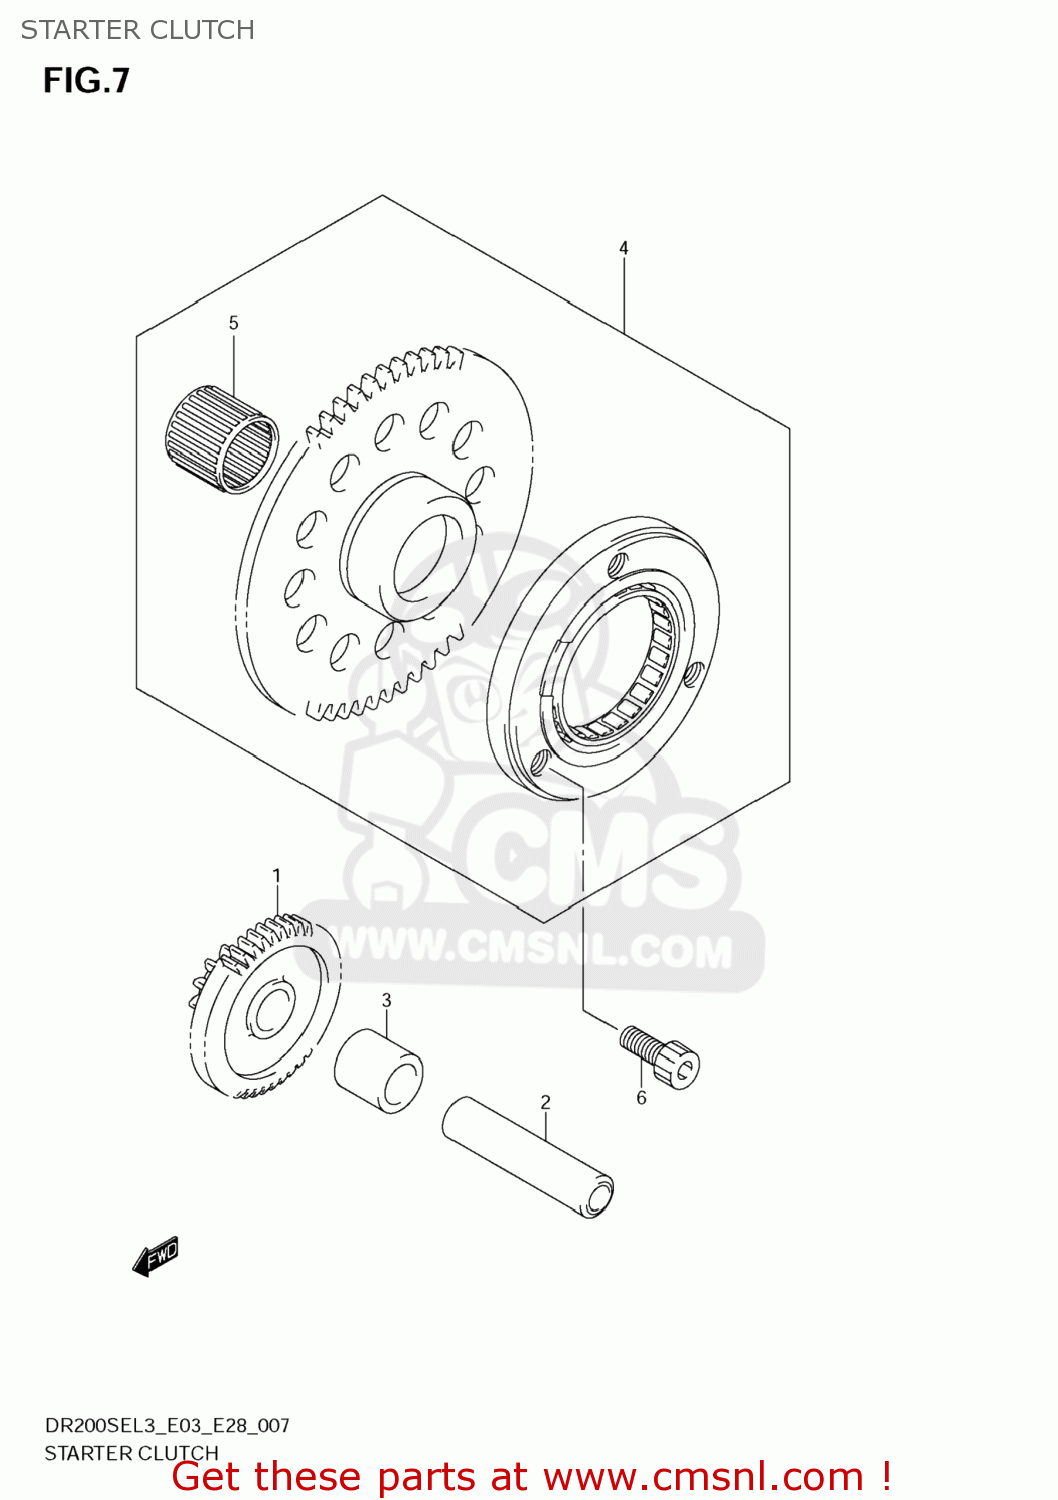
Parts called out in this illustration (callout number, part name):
1	GEAR,STARTER IDLE
2	PIN(7.4X13X56)
3	SPACER(13X19X19)
4	CLUTCH SET,STARTER
5	BEARING(22X28X16)
6	BOLT(8X16)
